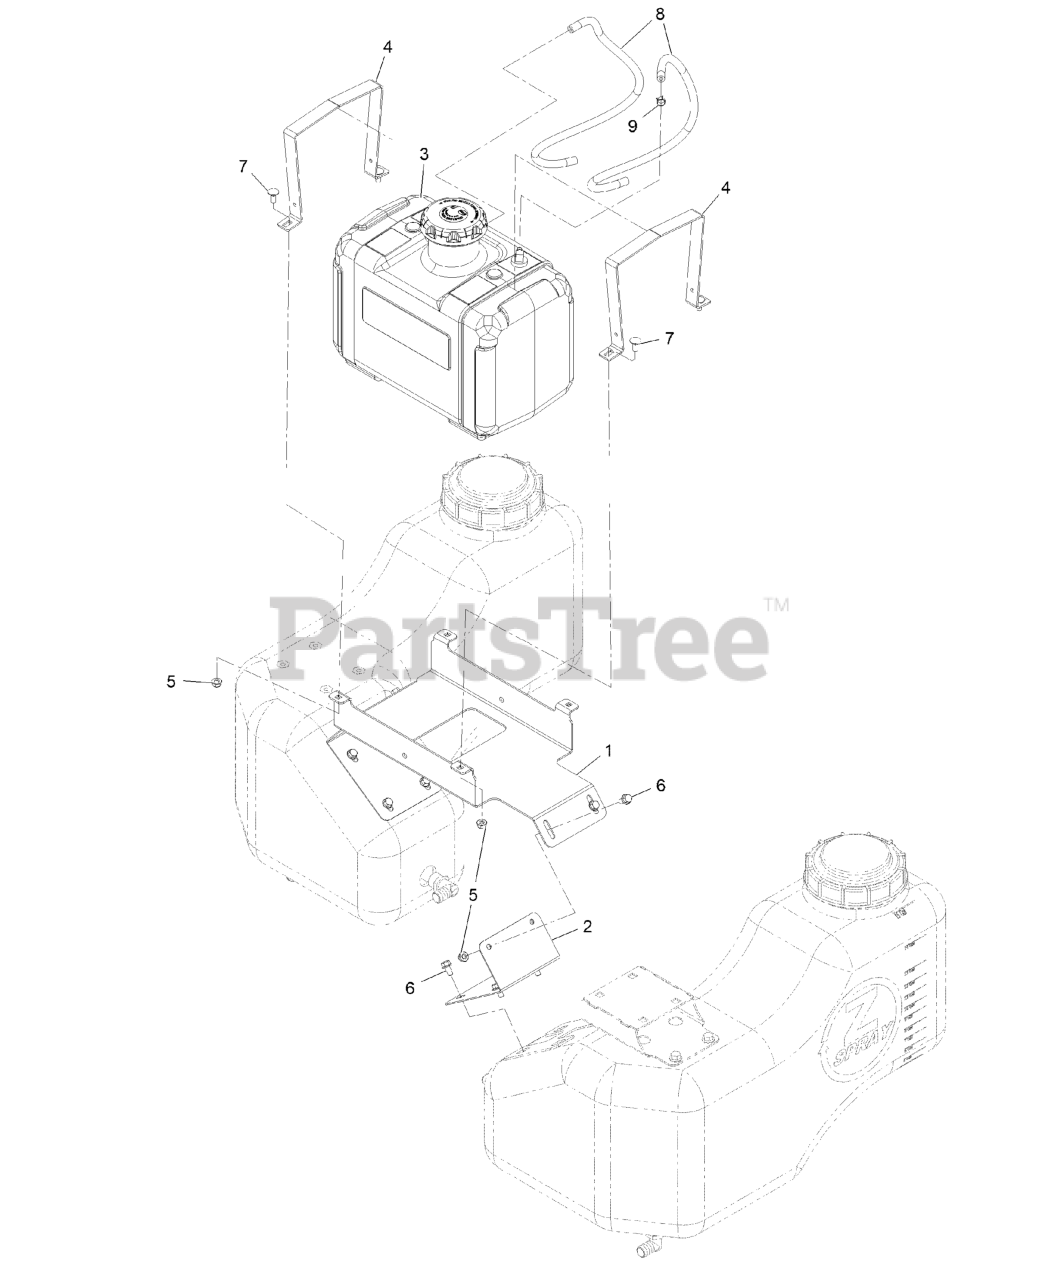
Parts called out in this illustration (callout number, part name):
1	Mount-Tank, Fuel
2	BRACKET-SUPPORT, GAS TANK
3	ASM-Tank, 5 Gal.
4	Strap, Gas Tank
5	Nut-Hex Flange
6	Screw-HHF
7	SCREW-CARR
8	HOSE-FUEL
9	CLAMP-HOSE
